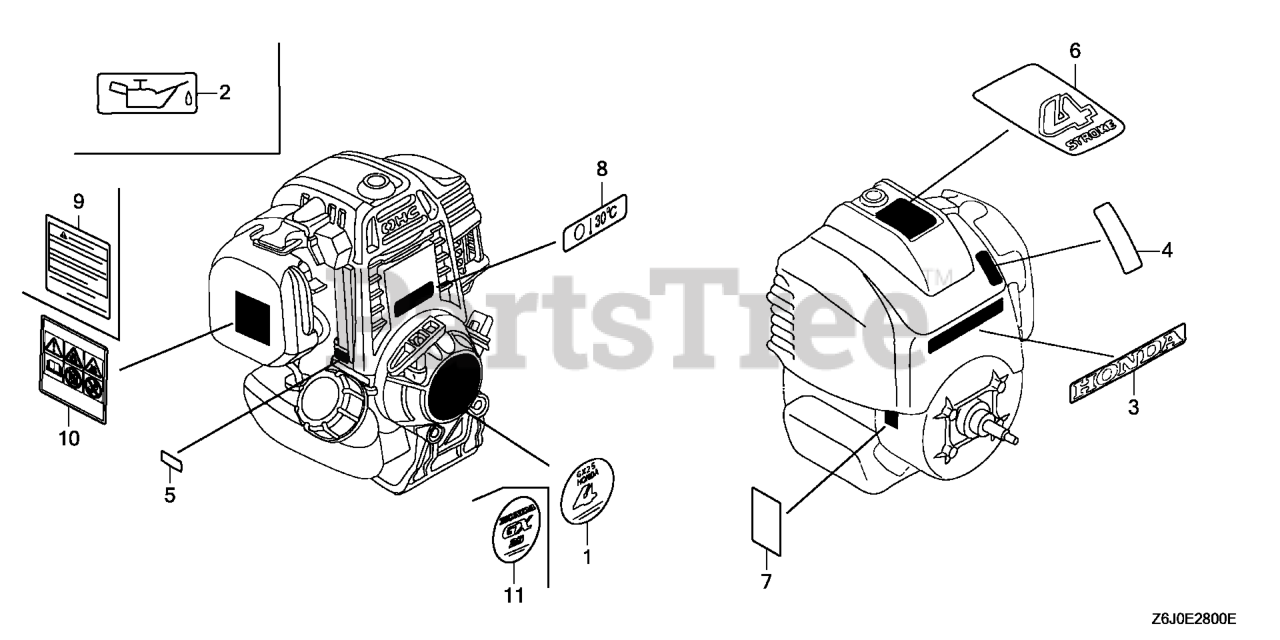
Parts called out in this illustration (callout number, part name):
2	MARK, OIL CAUTION
4	MARK, THROTTLE INDICATION
5	MARK, TYPE (W3)
6	MARK (4-STROKE)
7	LABEL, WARNING (NOT CERTIFIED FOR SALE)
9	MARK, OPER CAUTION
10	MARK, OPER CAUTION
11	MARK, EMBLEM
